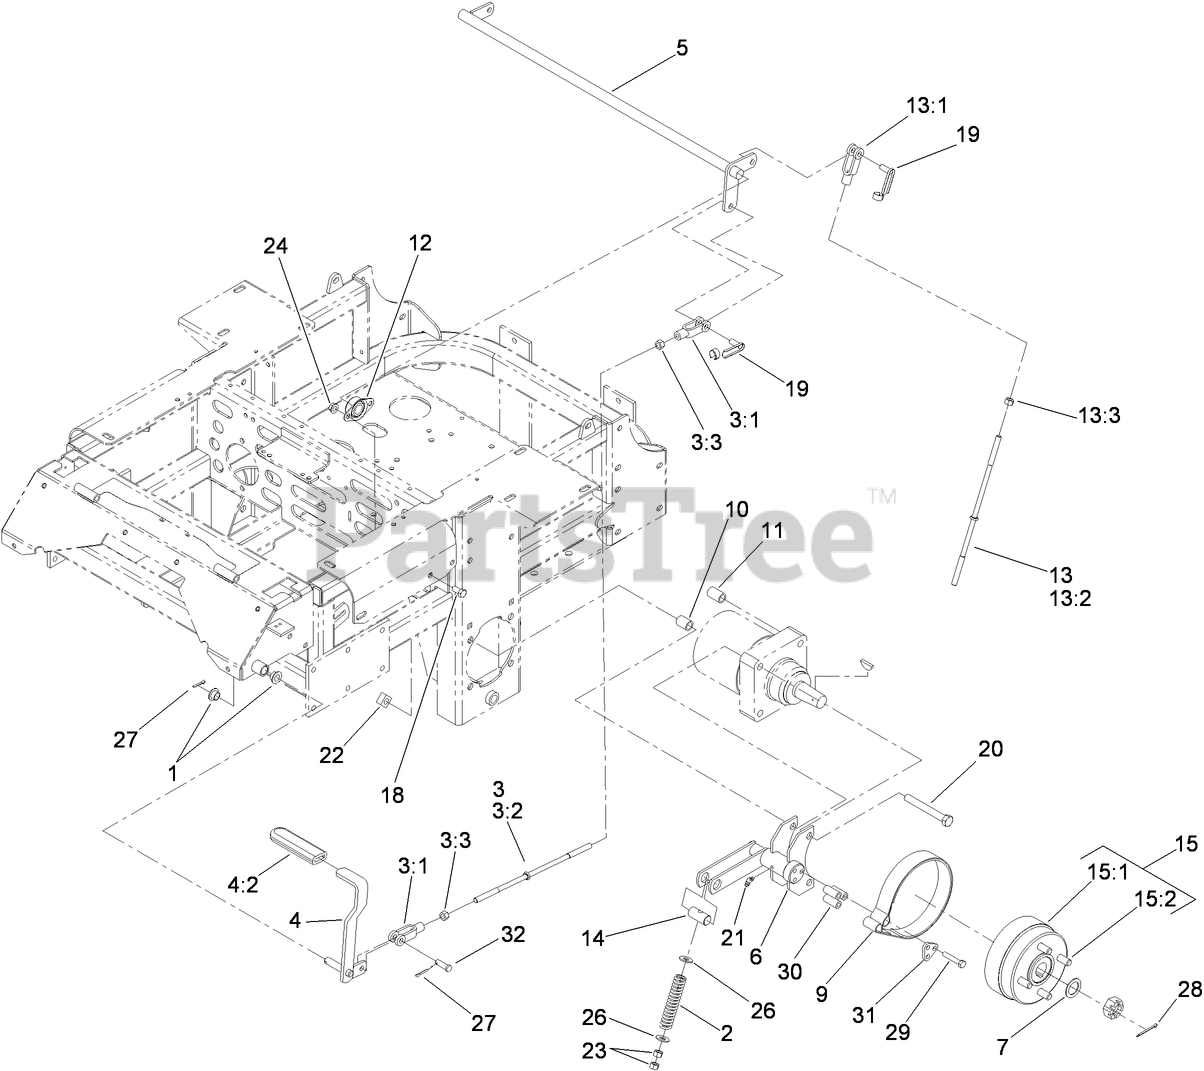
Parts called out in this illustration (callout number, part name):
1	BEARING-CONTROL
2	SPRING-BRAKE
3	Brake Rod And Yoke ASM
3:1	YOKE-LINKAGE, BRAKE
3:2	ROD-BRAKE
3:3	NUT-HEX
4	BRAKE LEVER ASM
4:2	GRIP-LEVER
5	SHAFT-BRAKE
6	BRACKET-BRAKE
7	WASHER-SPACER
9	BAND-BRAKE
10	SPACER-WHEEL, SHORT
11	SPACER-WHEEL, LONG
12	BEARING-FLANGE, SIDE
13	Brake Rod And Yoke ASM
13:1	YOKE-LINKAGE, BRAKE
13:2	ROD-BRAKE
13:3	NUT-HEX
14	PIN-TRUNION
15	WHEEL HUB ASM
15:1	HUB-WHEEL
15:2	STUD-WHEEL
18	SCREW-HH
19	Pin-Spring, Clevis
20	SCREW-HH
21	FITTING-GREASE
22	NUT-SQUARE, SPECIAL
23	NUT-HEX
24	NUT-HHF, WHIZ
26	WASHER-FLAT
27	PIN-COTTER
28	PIN-COTTER
29	SCREW-HH
30	SPACER
31	RETAINER-BAND, BRAKE
32	PIN-CLEVIS
